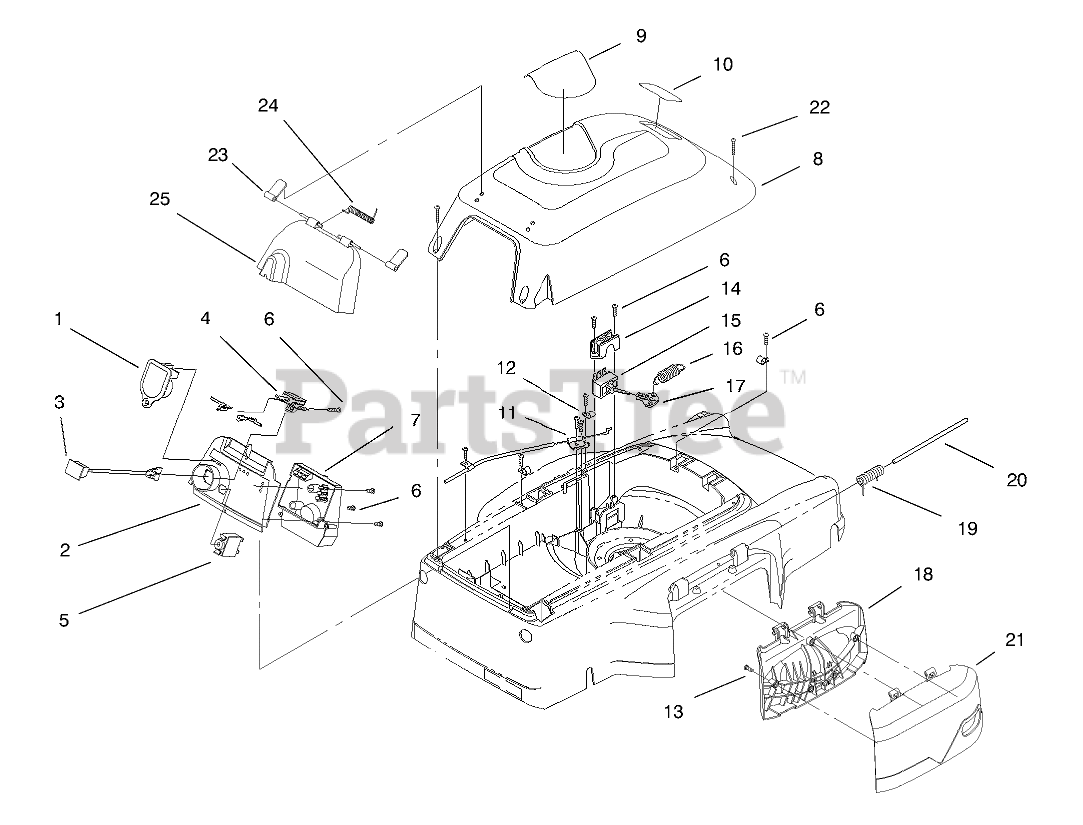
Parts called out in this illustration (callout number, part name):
2	ASM - 24V PANEL 46CM
3	PLUG ASM
4	HOUSING - PLUG
5	CIRCUIT BREAKER
6	SCREW-PPH
7	ASM-CIRCUIT BOARD SERVICE
8	COVER ASM
9	DECAL - COVER
10	PLATE-LOGO
11	BRACKET - CABLE
12	CLIP - WIRE
13	SCREW
14	CLAMP - SWITCH, TOGGLE
15	SWITCH - TOGGLE
16	SPRING - SWITCH
17	COVER LEVER-SWITCH
18	OBS MULCH PLUG - INSIDE
19	SPRING - TORSION
20	PIN - HINGE, MULCH PLUG
21	PLUG - OUTSIDE MULCH
22	SCREW-PPH
23	TAB - SHIELD
24	SPRING - TORSION, SHIELD
25	SHIELD - RAIN
